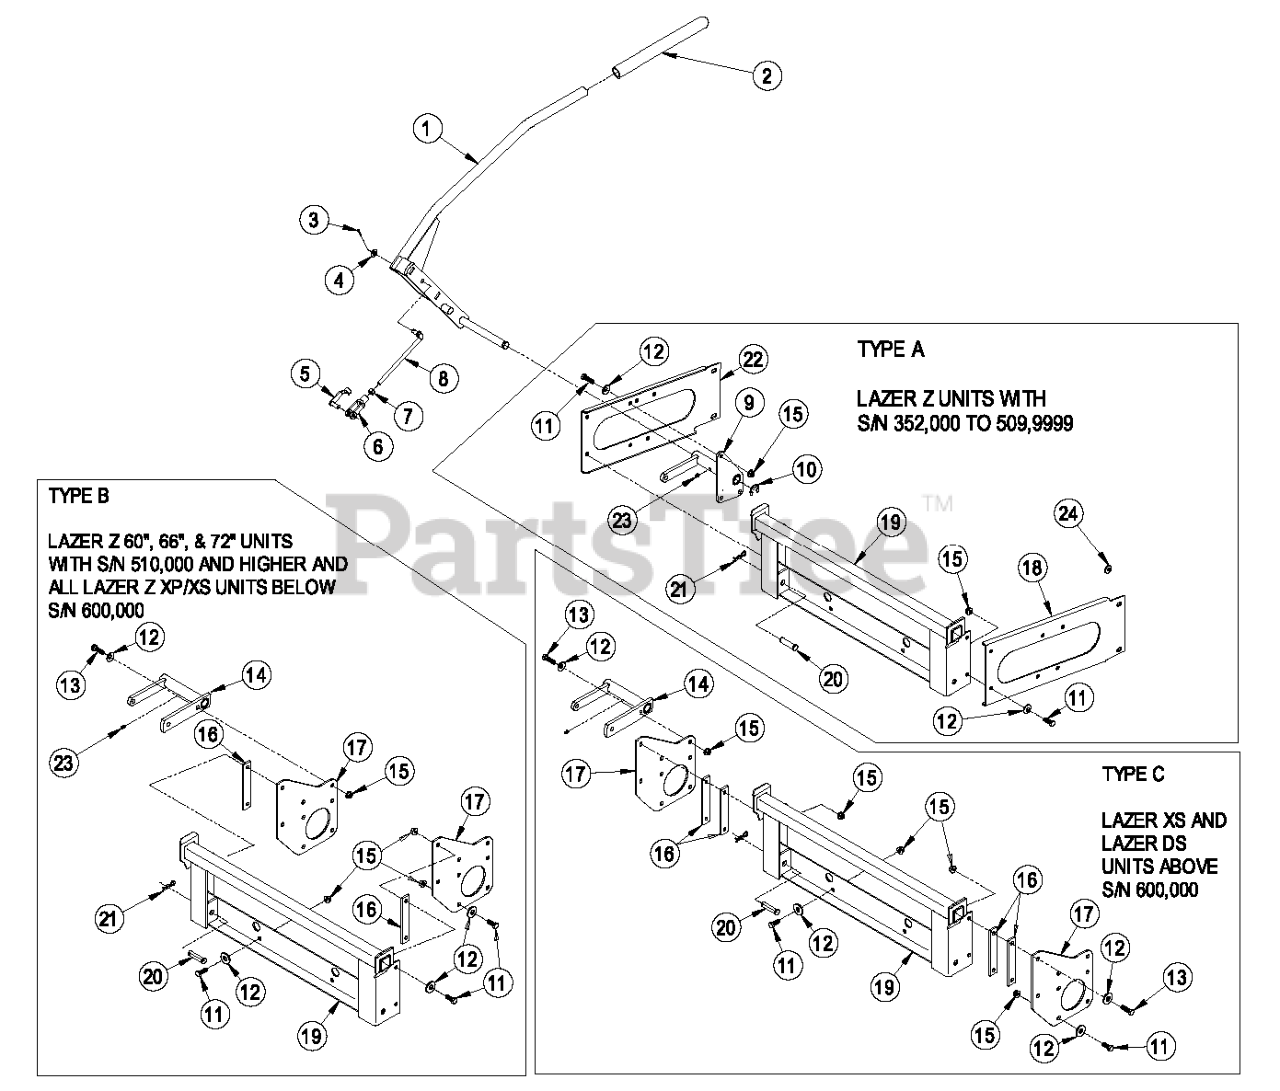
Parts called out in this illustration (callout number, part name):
1	HANDLE AND GRIP ASM
2	GRIP-HANDLE
3	PIN-COTTER
4	WASHER-FLAT
5	PIN-SPRING, CLEVIS
6	YOKE-LINKAGE, BRAKE
7	NUT-HEX
8	LINK-HANDLE
9	WLD, HANDLE MOUNT
11	SCREW-HH
12	WASHER-BELLEVILLE
13	SCREW-HH
14	WLD, HANDLE MOUNT - XP
15	NUT-HHF, WHIZ
17	PLATE-MOUNT, BAGGER
18	BRACKET-FRAME, RH
19	MOUNT-BAGGER
20	PIN-CLEVIS
21	PIN-COTTER
22	BRACKET-FRAME, LH
23	FITTING-GREASE
